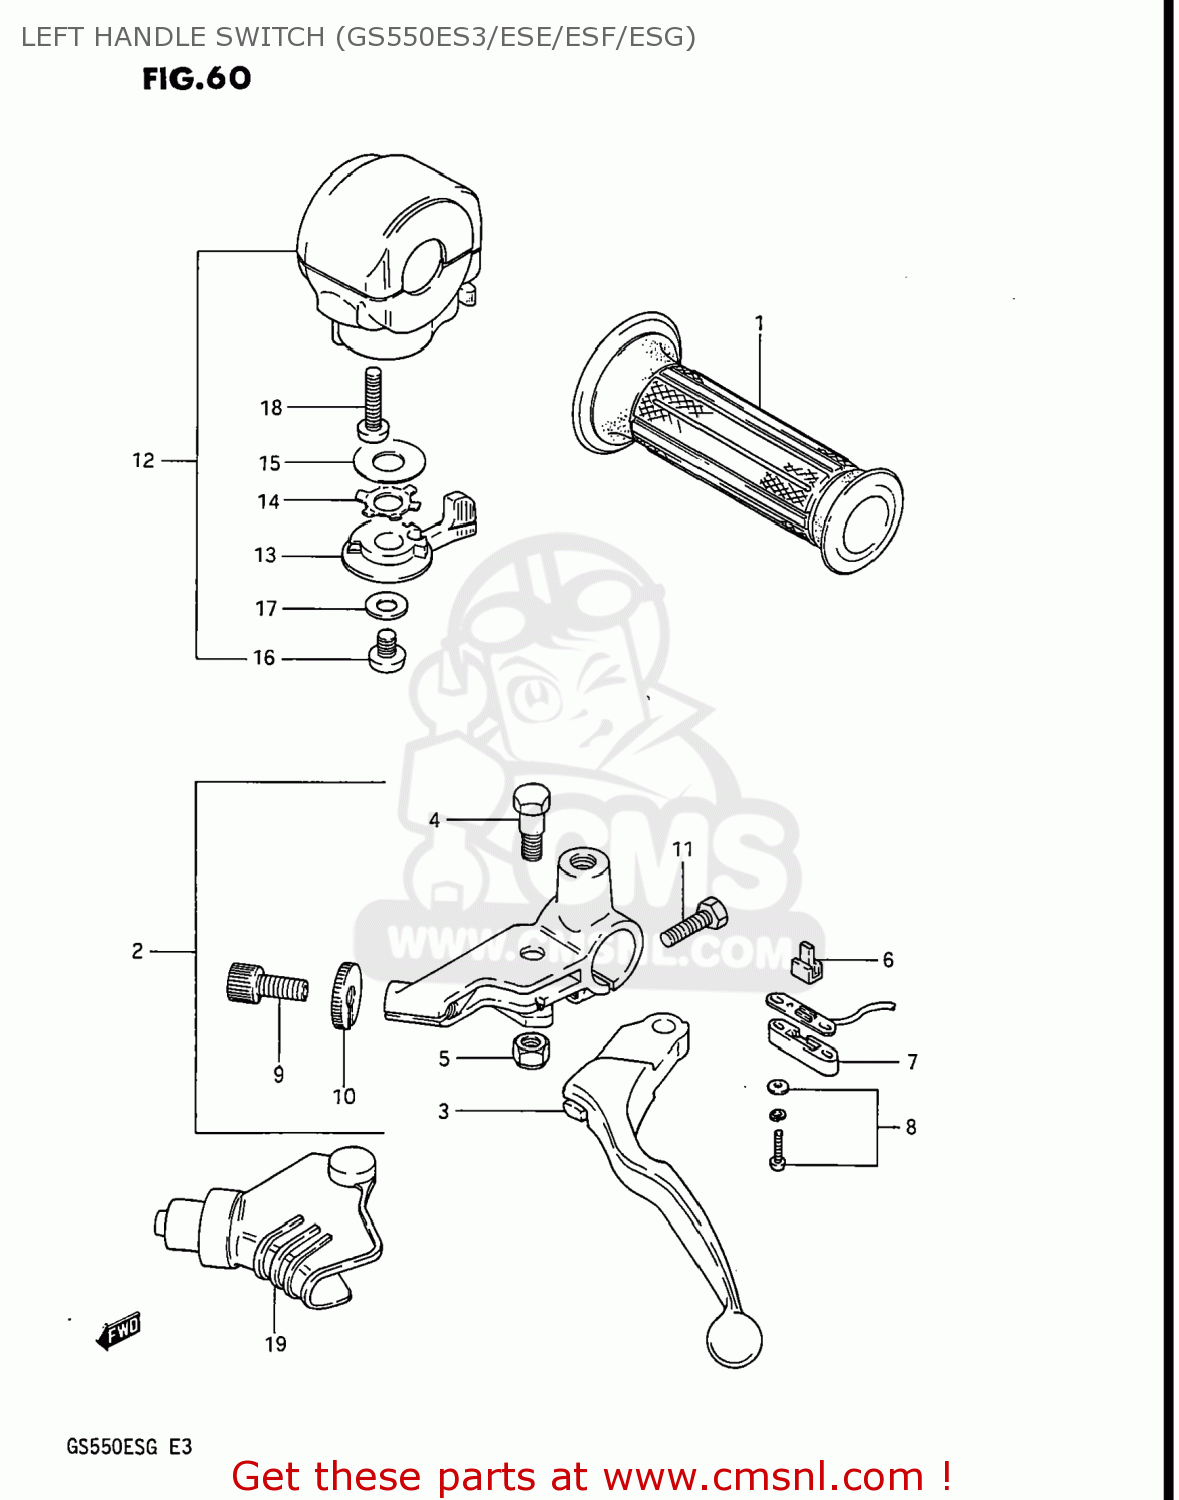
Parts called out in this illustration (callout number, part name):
1	GRIP,L
2	CLUTCH LEVER & SWITCH ASSY
3	LEVER,CLUTCH
4	BOLT,LEVER
5	NUT
6	CONTACT,SWITCH
7	COVER,FR BK TERMINAL BASE
8	SCREW
9	ADJUSTER,CABLE
10	NUT,CABLE ADJUSTER
11	BOLT
12	SWITCH ASSEMBLY,HANDLE,LEFT
13	LEVER,STARTER
14	WASHER
15	WASHER
16	SCREW
17	WASHER
18	SCREW
19	COVER,CLUTCH LEVER
